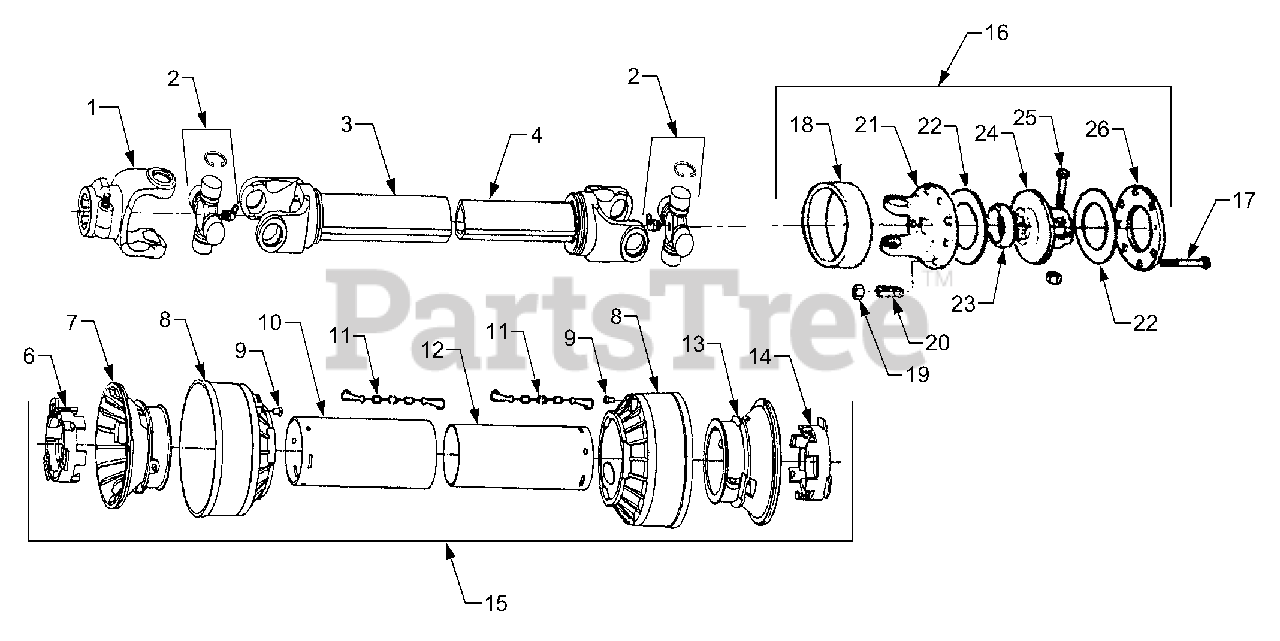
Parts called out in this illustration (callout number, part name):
1	Yoke 1 3/8 6
2	Cross, Bearing
3	Outer Tube & Yoke
4	Inner Tube & Yoke
6	Tube Bearing Outer
7	Outer Tube Rigid Cone
9	Pin For Stop Rotation
10	Outer Shield
12	Inner Shield
13	Inner Tube Rigid Cone
14	Tube Bearing Inner
15	Shield Complete
16	Slip Clutch Yoke Complete
17	Bolt M10x80
18	Dirt Shield
19	Nut 10MM Nylock
21	Yoke Slip Clutch
22	Friction Disk
24	Body Friction Clutch
25	Bolt M12x65 With Nut
26	Outer Flange
